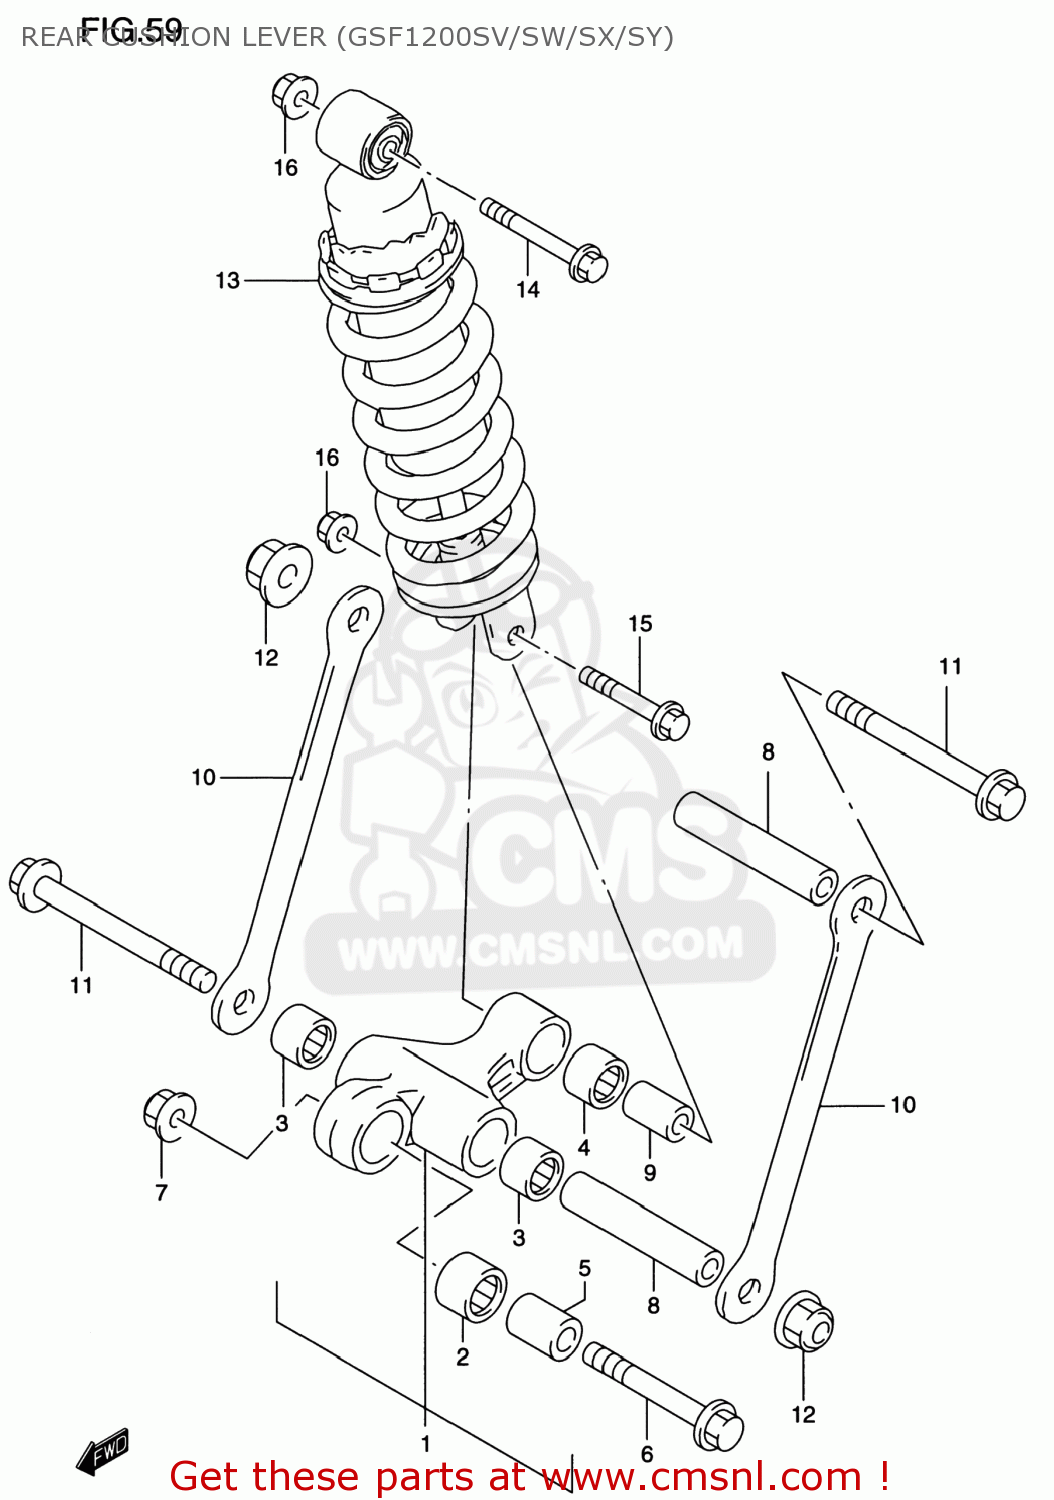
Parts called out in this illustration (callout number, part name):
1	LEVER SET,RR CUSHION
2	BEARING(20X27X26)
3	BEARING(17X24X25)
4	BEARING(17X24X26)
5	SPACER,RR CUSHION LEVER FR
6	BOLT,CUSHION LEVER FR
7	NUT 12MM
8	SPACER(12X17X85)
9	SPACER,RR CUSHION LEVER
10	ROD,RR CUSHION LEVER
11	BOLT(12X115)
12	NUT 12MM
13	ABSORBER ASSEMBLY,REAR SHOCK
14	BOLT(10X50)
15	BOLT(10X54)
16	NUT
